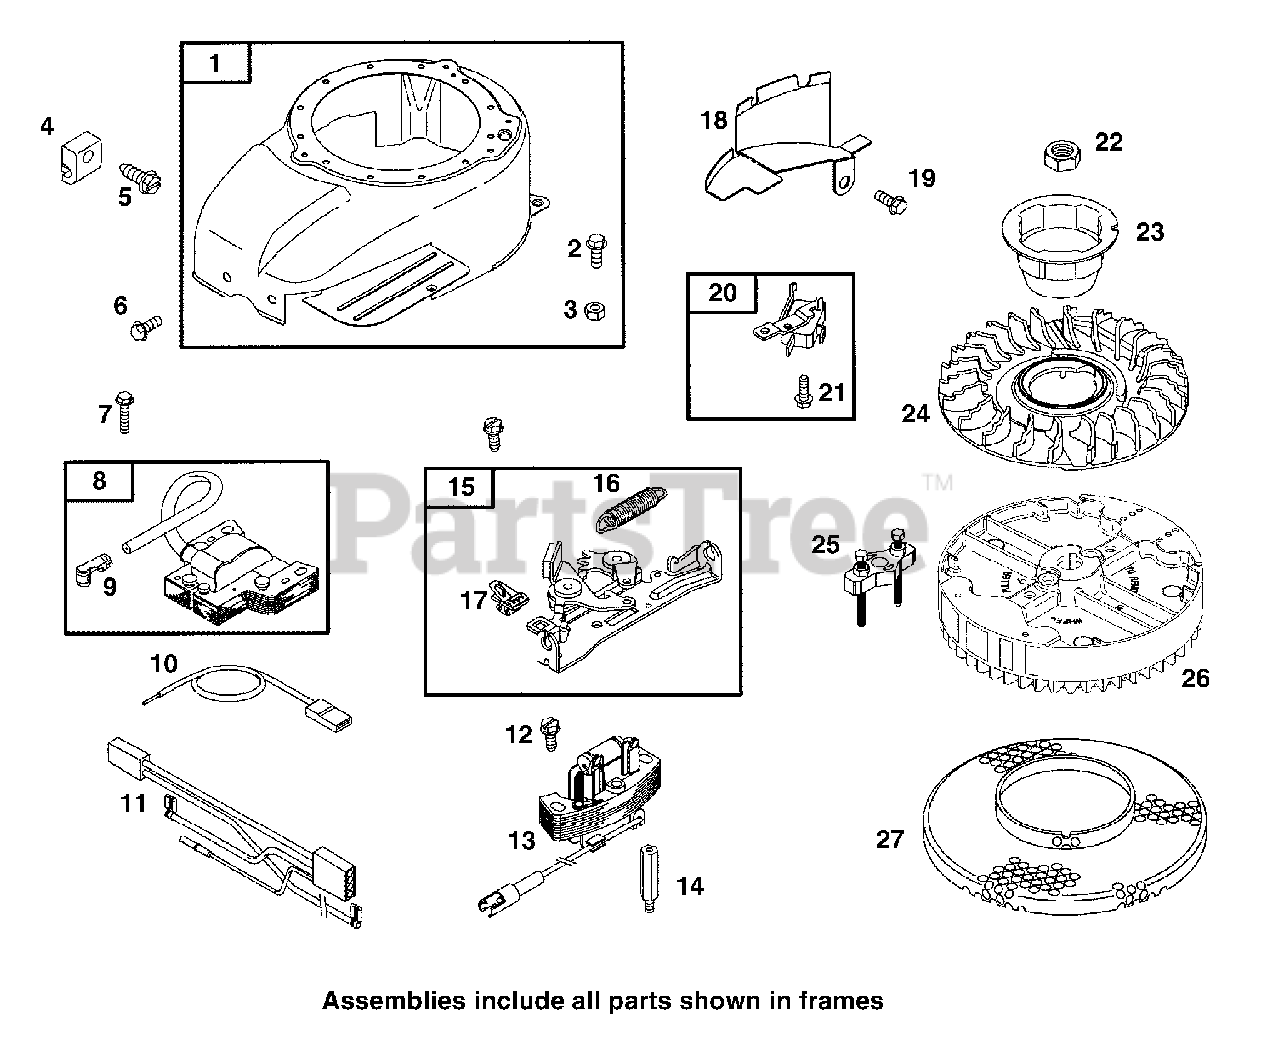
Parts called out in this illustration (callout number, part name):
1	Blower Housing
2	Hex Screw
3	Hex Screw
4	Casing Clamp
5	Slotted Hex Screw
6	Hex Screw
7	Hex Screw
8	Magneto Armature
9	Cable Terminal
10	Wiring Stop
11	Wiring Harness
12	Slotted Hex Screw
13	Alternator
14	Stud
15	Brake
16	Brake Spring
17	Stop Switch
18	Flywheel Guard
19	Hex Screw
20	Interlock Switch
21	Hex Screw
22	Flywheel Nut
23	Flywheel Cup
24	Flywheel Fan
25	Flywheel Puller
26	Flywheel
27	Rotating Screen
